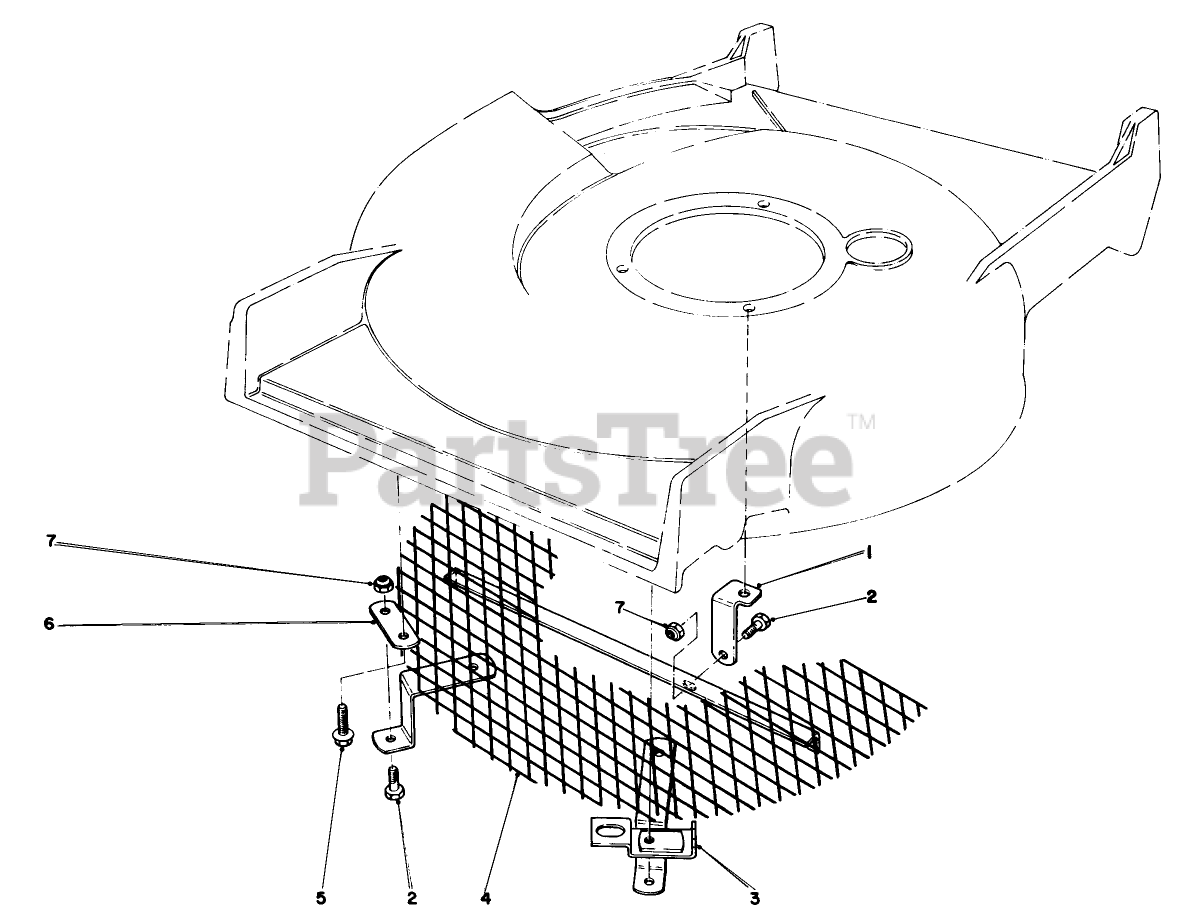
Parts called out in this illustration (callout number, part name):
2	SCREW-HH
3	MTG. BRACKET W.A.
5	SCREW-THD ROLL, HWH
7	NUT-LOCK, NI
